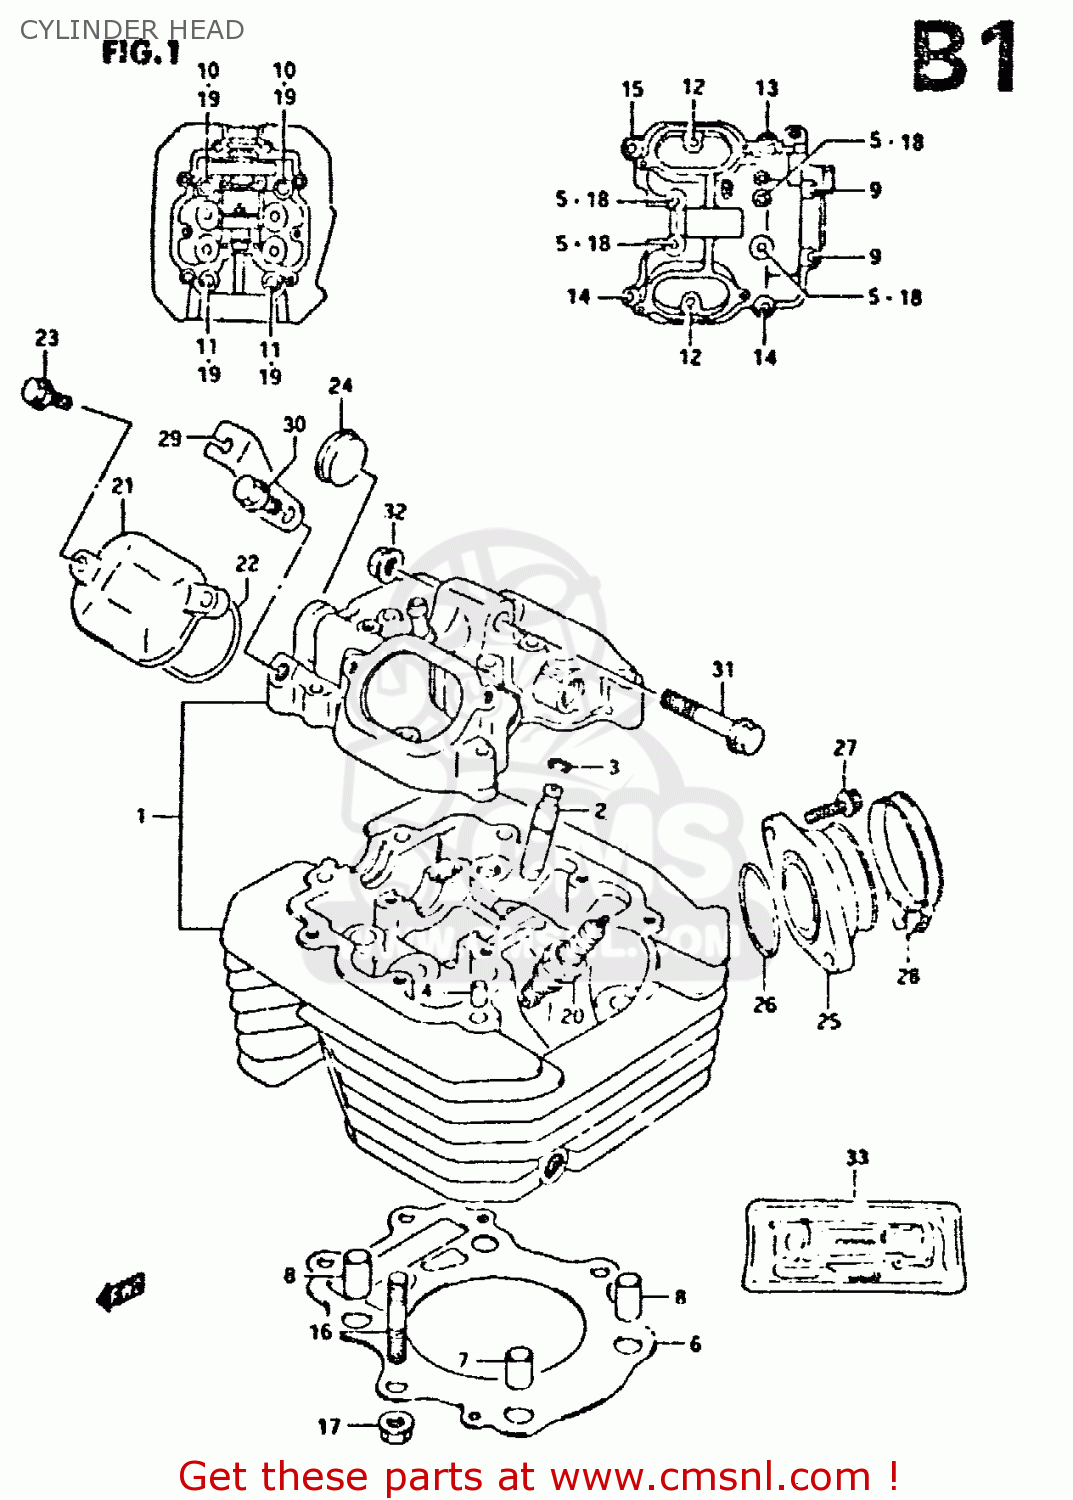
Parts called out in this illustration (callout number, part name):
1	HEAD ASSEMBLY,CYLINDER
2	GUIDE,VALVE
3	RING,SNAP
4	PIN(6.2X8X11)
5	BOLT(6X55)
6	GASKET,CYLINDER HEAD (NAS)
7	PIN
8	PIN(10.4X13X22)
9	BOLT(6X115)
10	BOLT(10X180)
11	BOLT(10X155)
12	BOLT
13	BOLT
14	BOLT(6X35)
15	BOLT(6X39)
16	BOLT,STUD
17	NUT
18	GASKET(5.8X13X1.2) (NAS)
19	WASHER (10.5X22X2.3)
20	PLUG,SPARK(DPR8EA-9)
21	CAP,INSPECTION
22	O RING,INSPECTION CAP
23	BOLT
24	PLUG, HEAD
25	PIPE ASSEMBLY,INTAKE
26	O RING(D:2.4,ID:39.7)
27	BOLT
28	CLAMP
29	LEVER,DECOMP SHAFT RH
30	BOLT
31	BOLT(8X65)
32	NUT
33	GASKET SET (NAS)
